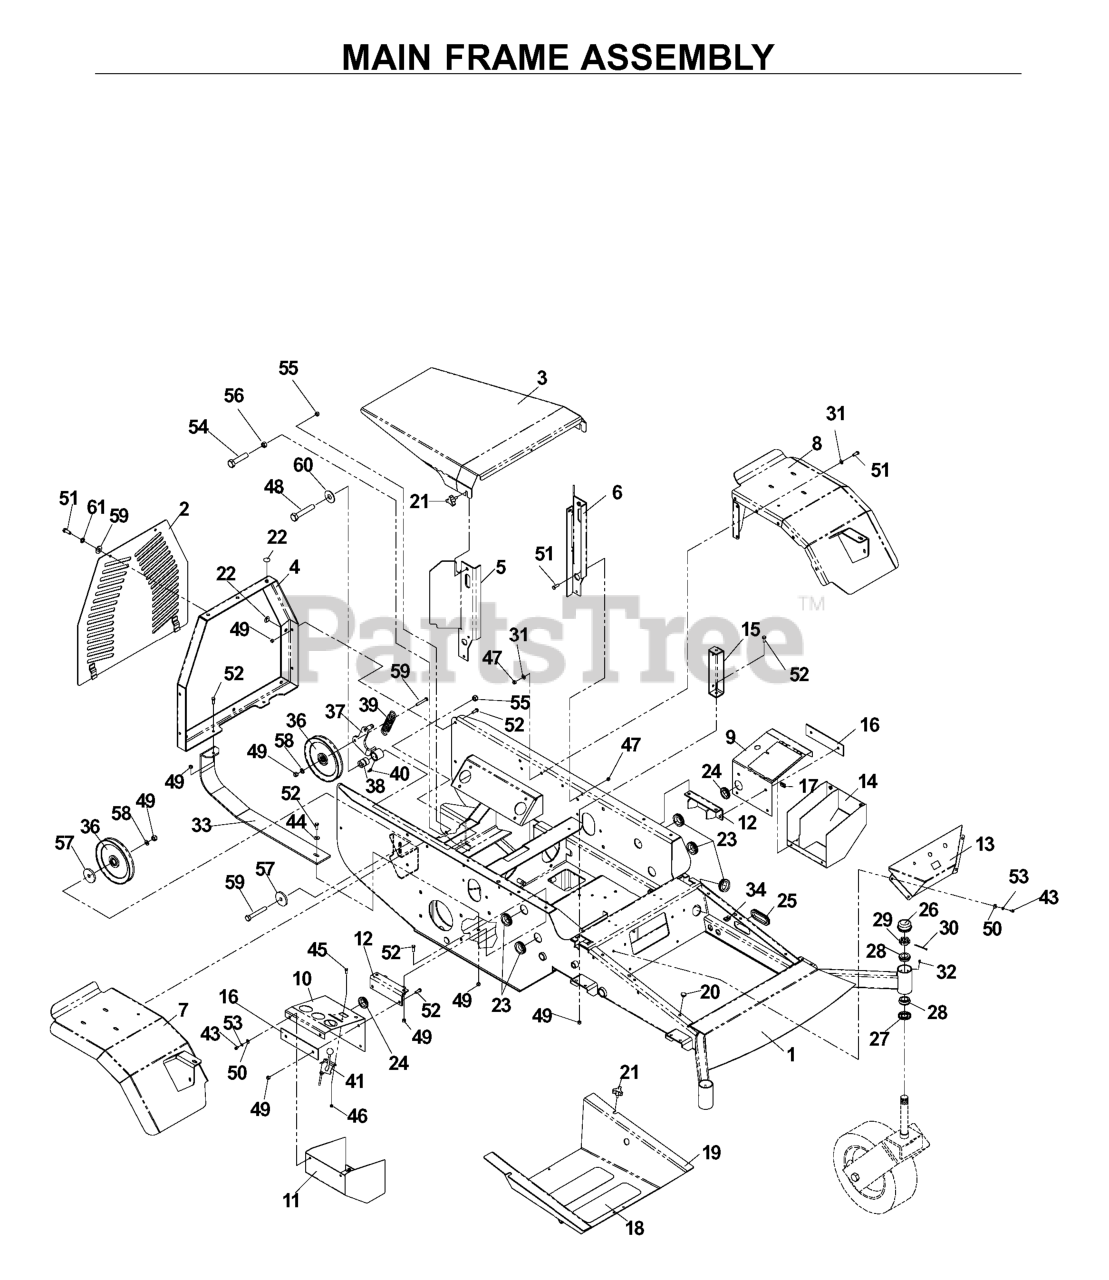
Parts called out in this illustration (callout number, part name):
1	FRAME W/DECALS
2	PANEL W/ DECALS
3	HOOD ORANGE
4	REAR FRAME
5	SUPPORT WLDMT, RT
6	SUPPORT WLDMT, LT
7	FENDER WELDMT, RH
8	FENDER WELDMT, LH
10	CONSOLE TOP-PAINTED
11	CONSOLE BOTTOM
12	MTG ANGLE WELDMT
13	CENTER CONSOLE WELDMENT
14	BOTTOM CONSOLE
15	SUPPORT WELDMENT
16	BLACK-STIFFNER-PAINTED
17	MAGNETIC LATCH
18	ANTI-SKID PAD
19	FOOT PLATE WIDMT
20	GROMMET, BUMPER
21	KNOB W/STUD
22	GROMMET BUMPER
26	GREASE CAP
28	TAPERED ROLLER BRG
29	NUT 1"C HEX SLOTTED
30	COTTER PIN 1/8 X 2
31	FLAT WASHER 5/16 SAE
33	SKID PLATE
34	U-CLIP 5/16-18 NUT RETAINER
36	IDLER PULLEY
37	ARM WELDMENT
40	ZERK
41	THROTTLE CONTROL W/BALL KNOB
43	SCREW 1/4 X 5/8
44	WASHER 3/8 FLAT
45	HCS #10-24 X 1/2
46	NUT 10-24 NYLOC
47	NUT 5/16 NYLOC
48	HEX SCREW 1/2-13 X 2.5" GR 5
49	NUT 3/8-16 NYLOC
50	WASHER 1/4 FLAT
51	HCS 5/16C X 1
52	HCS 3/8-16X1.GRD.5.ZD
53	LOCKWASHER 1/4"
54	HCS 1/2-13X2 GR 8
55	NUT 1/2-13 HEX NYLOC ZD
56	NUT HEX 1/2
57	SPINDLE WASHER
58	WASHER 3/8 SAE FLAT
59	WASHER 5/16 FLAT
60	WASHER 1/2 FLAT
61	WASHER.LOCK.HVY.HLCL.SPR.5/16
539976856	TIE, PLASTIC
